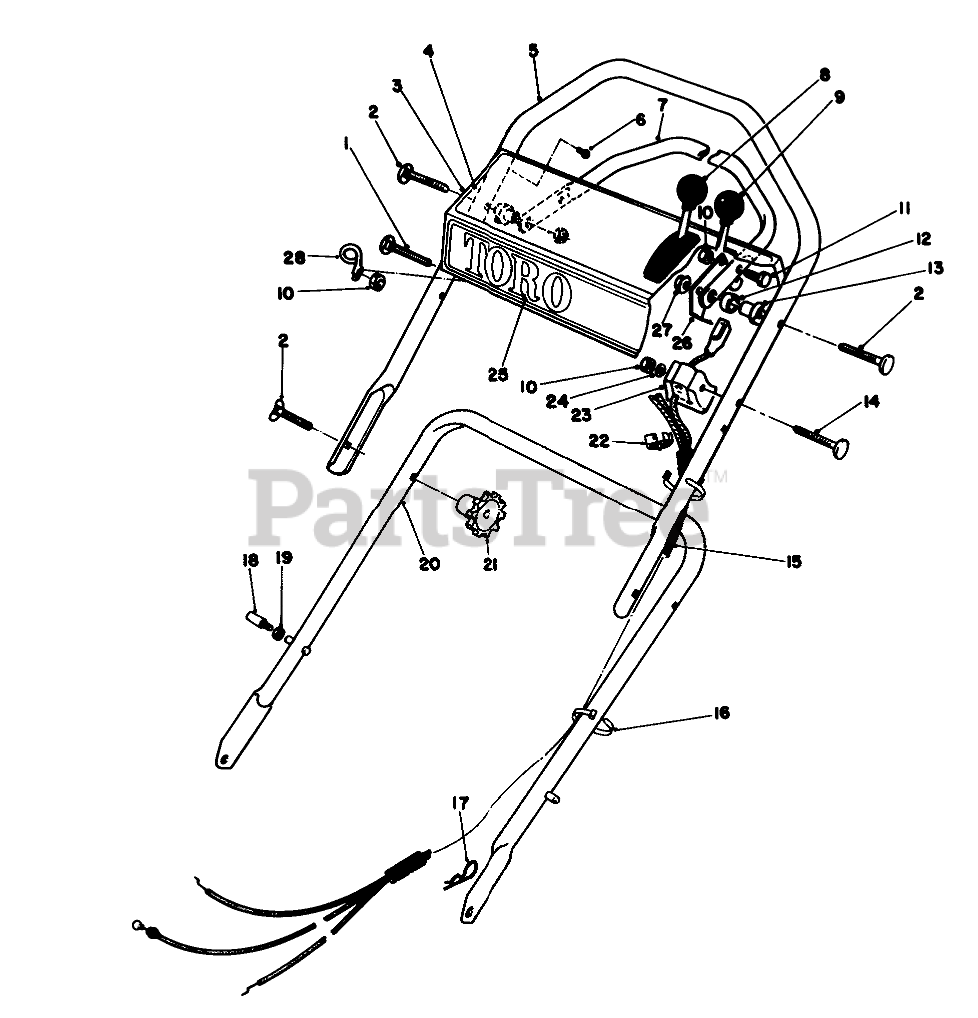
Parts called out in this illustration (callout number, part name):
1	HANDLE SCREW
2	5/16-18 X 2 HNDLE SCREW
3	Panel-Control (Incl. Ref. #4)
4	Decal-Instructions
5	Handle-Upper
6	SCREW-HWHTF
7	Bar-Control
8	SERVICE TRACT. CONTROL
9	Control-Throttle/Choke Bend Type 2 Sheath Lg.41" (104.1 cm) Wire Lg.21/4" (5.7 cm)
10	NUT-LOCK, NI
11	SCREW-HH
12	SPACER-NYLON
13	SPACER-SUPPORT
14	HANDLE SCREW
15	CONT. CABLE COVER
16	TIE-CABLE
17	Hairpin Cotter
18	CHOKE DECAL
19	NUT-LOCK, NI
20	LOWER HANDLE ASM
22	FITTING-RING
23	SUPPORT-CABLE
24	WASHER-FLAT
25	Decal-Toro
26	LEVER-CONTROL
27	NUT-LOCK, NI
28	Guide
